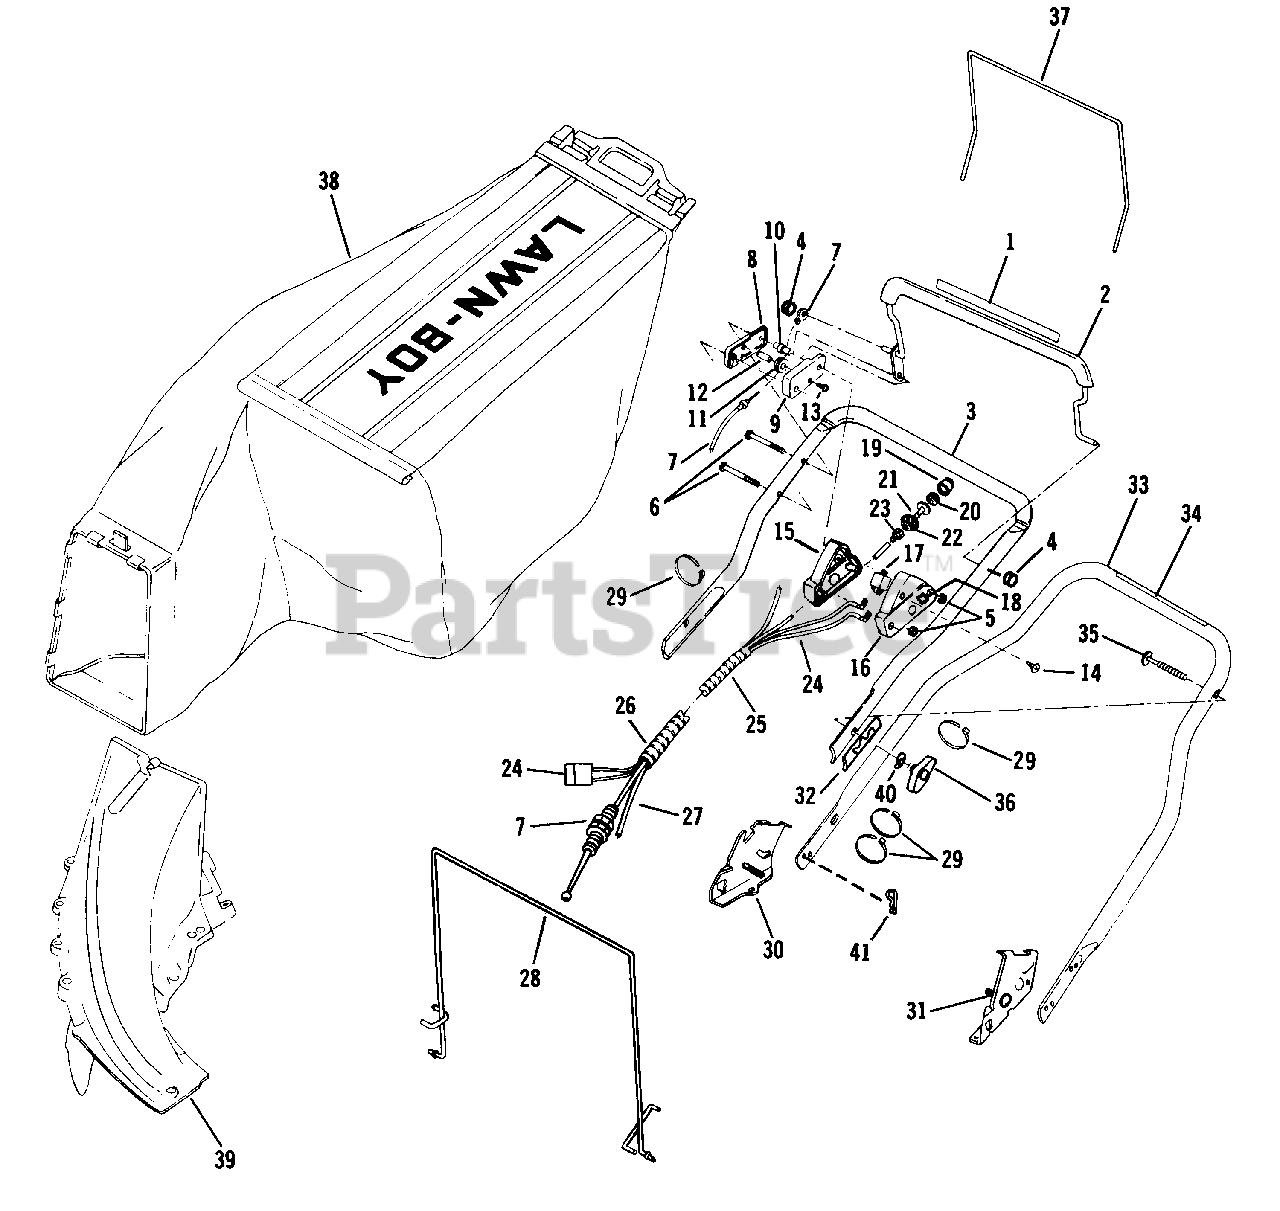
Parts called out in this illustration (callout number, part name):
1	Decal-Blade Control
2	Control Lever Assembly
3	Top Handle and Grip Assembly
4	Pushnut
5	Nut-Hex-Centerlock
7	Control Cable Assembly
8	Control Case-Outer
9	Control Case-Inner
11	Pulley
15	Console-R.H.
16	Console-L.H.
17	Switch Assembly
19	Primer Bulb
21	Primer Base
23	Locknut
24	Wire Harness Assembly
25	Spiral Tubing
26	Spiral Tubing
27	Tubing-Primer
28	Hanger Assembly-Front
29	Tie Strap
30	Handle Bracket-R.H.
31	Handle Bracket-L.H.
32	Bracket
33	Handle-Bottom
34	Decal-Starting Inst.
35	Screw-Folding Handle
38	Bag Assembly
39	Chute Assembly
41	Hair Pin
